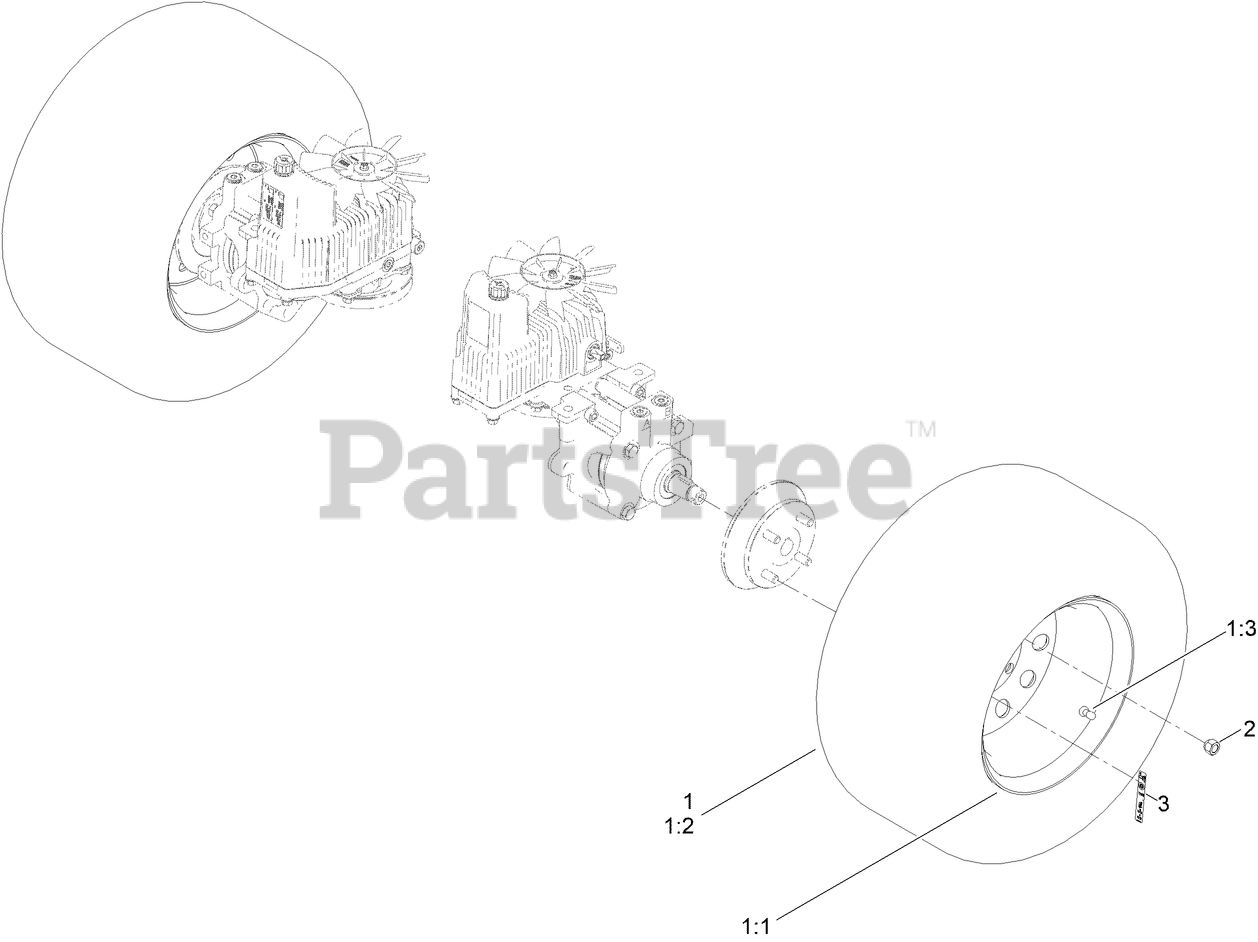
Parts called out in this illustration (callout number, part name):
1	WHEEL AND TIRE ASM
2	NUT-LUG
3	DECAL-TORQUE, WHEEL HUB LUG
